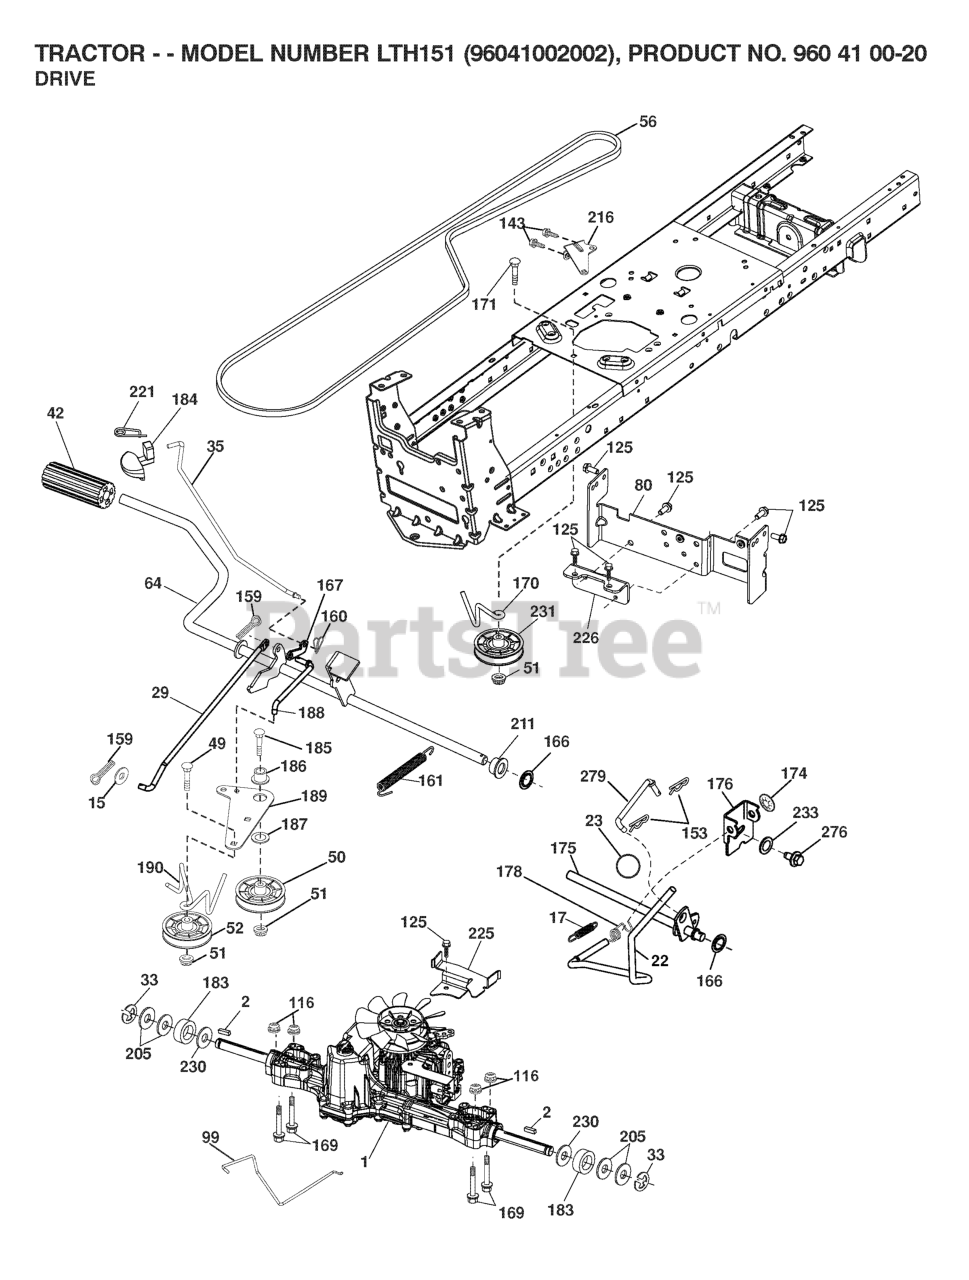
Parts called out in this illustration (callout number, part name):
2	SQUARE KEY
15	WASHER
17	SPRING.BRAKE.K46.GREEN
22	ROD.SHIFT.FENDER.TLT.2006
23	KNOB.DUCKHEAD.1/2
29	ROD.BRAKE.K46
35	ROD.CNTRL.PARK.PREDATOR.LT.TEX
42	PEDAL COVER T
50	IDLER.FLAT.910.OFFSET
51	NUT LOCK FLG 3/8-16 UNC
52	IDLER.V-GROOVE.910.OFFSET
56	V-BELT.MOWER.92.40.42/K46
64	SHAFT.ASM.PEDAL.BRAKE.
80	STRAP TORQUE
99	ROD ASM BYPASS
116	NUT LOCK HEX FLANGE 5/16-18
125	SCREW
143	Screw 5/16-18 x 1/2 Hex, Self Tapping 5/16-18 x 1/2
153	RETAINER M
159	COTTER PIN
160	RETAINER CLIP
161	SPRING, RETURN LT
162	SPACER.TRANSAXLE.18&22
166	NUT.PUSH.625.2006
167	LATCH.BRAKE.SPRING
169	BOLT HEX 5/16-18 GR 5
170	KEEPER.V-IDLER.CENTER.
174	NUT.PUSH.500.2006
175	SHAFT.ASM.SHFT.T2.TLT
176	ARM.CLEVIS.ROD.SHIFT
178	SPRING.SHIFT.GT2006
183	SPACER AXLE
184	HANDLE PARKING BRAKE
186	SPACER.RETAINER
187	WASHER 12/32X2X10GA
188	RP.LINK.CLUTCH.GROUND.DRIVE
189	BELLCRANK.GROUND.DRIVE.TEX.
190	KEEPER.BELLCRANK.DRIVE
211	BUSHING.SHAFT.BRAKE.HAND
216	BRACKET.PULLEY.IDLER.W/TEX
221	RETAINER.SPRING.CLIP.H
225	KEEPER.BELT.TRANSAXLE.K46
226	BRACKET.MOUNT.TORQUE.K46.TLT
230	WASHER.HARDENED
231	IDLER.V-GROOVE.1.688.OFFSET
233	WASHER SERRATED
276	BOLT FIN HEX 7/16-14 X 1
279	LINK.SHIFT.
